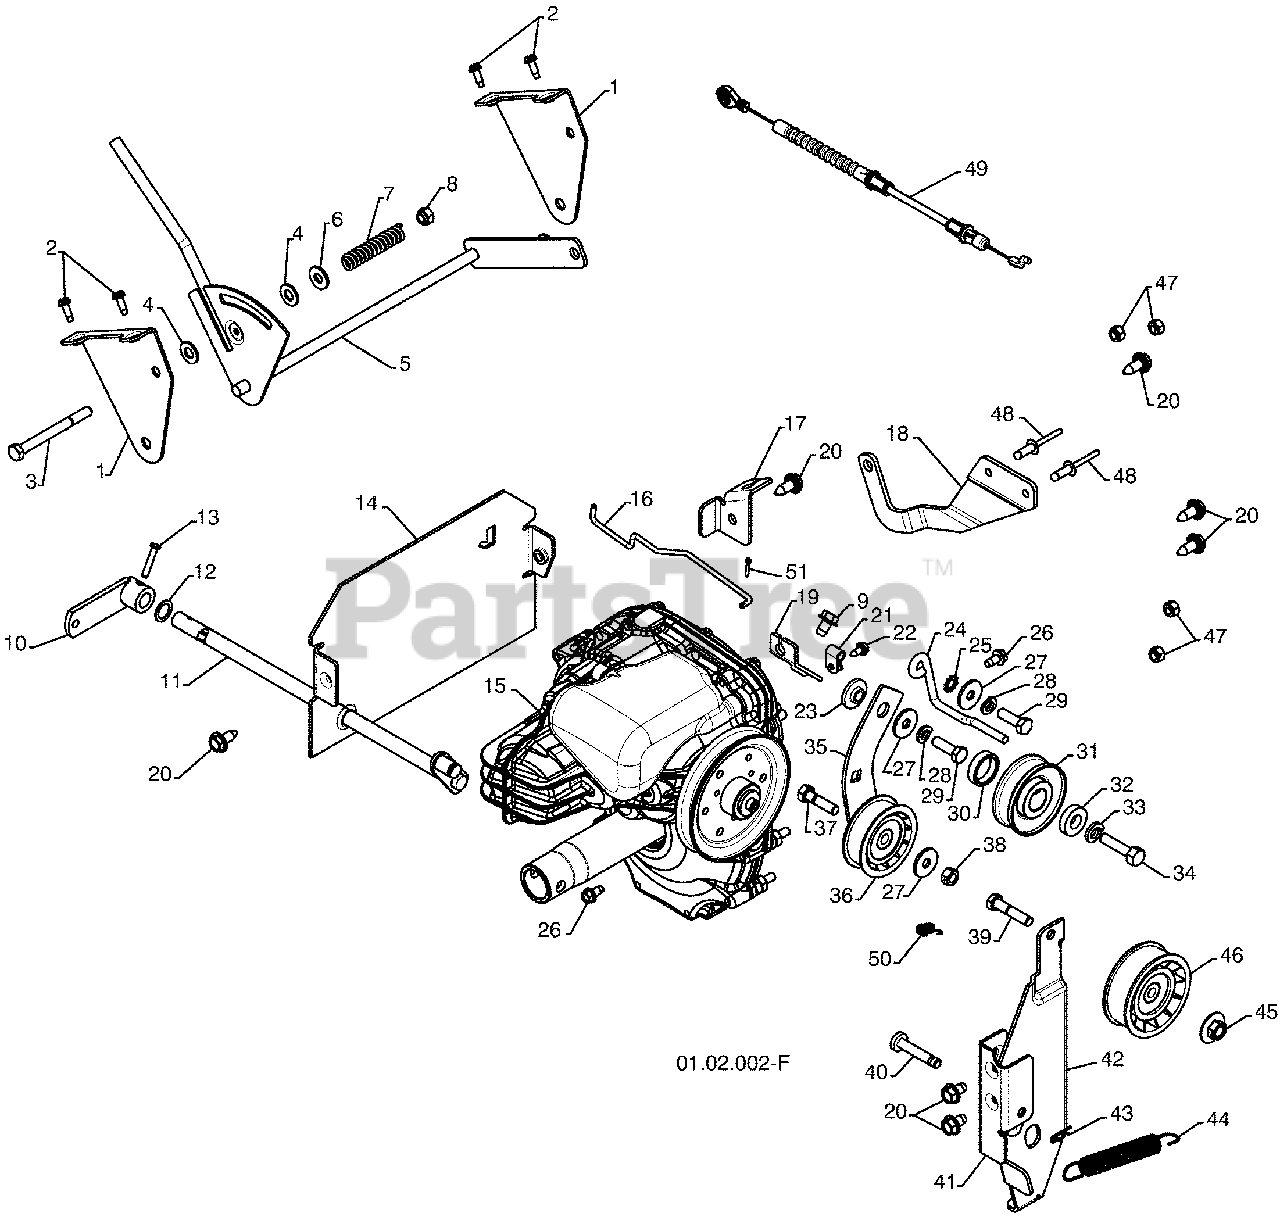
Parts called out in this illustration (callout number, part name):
1	SHIFT BRACKET
2	SCREW 10-24 X .625
3	SCREW 5/16-18 X 3.25
4	PLASTIC WASHER
5	SHIFT ASSEMBLY
7	FRICTION SPRING
8	NUT 5/16-18
9	BOLT 5/16-18 X .500
10	CONTROL ARM
11	CONTROL SHAFT
13	CLEVIS PIN
14	REAR PLATE
15	TRANSMISSION
17	REAR CABLE BRACKET
18	CONTROL ARM
19	FRONT CABLE BRACKET
20	SCREW 5/16-18 X .750
22	SCREW .12 X .50
23	BUSHING
24	BELT GUIDE
25	LOCKWASHER 5/16
26	SCREW 1/4-20 X .500
28	LOCKWASHER 5/16
29	SCREW 5/16-18 X 1.00
31	ENGINE TRACTION PULLEY
33	LOCKWASHER 3/8
34	SCREW 3/8-24 X 1.38
35	TRACTION IDLER ARM
36	IDLER PULLEY
37	SCREW 5/16-18 X 1.25
38	NUT 5/16-18
39	SCREW 5/16-18 X 1.50
41	IDLER PIVOT BRACKET
42	IDLER BRAKE ARM
44	BRAKE SPRING
45	NUT 5/16-18
47	NUT 1/4-20
48	POP RIVET 1/4 X .475
49	CLUTCH CABLE
50	TRACTION SPRING
51	RETAINER CLIP
